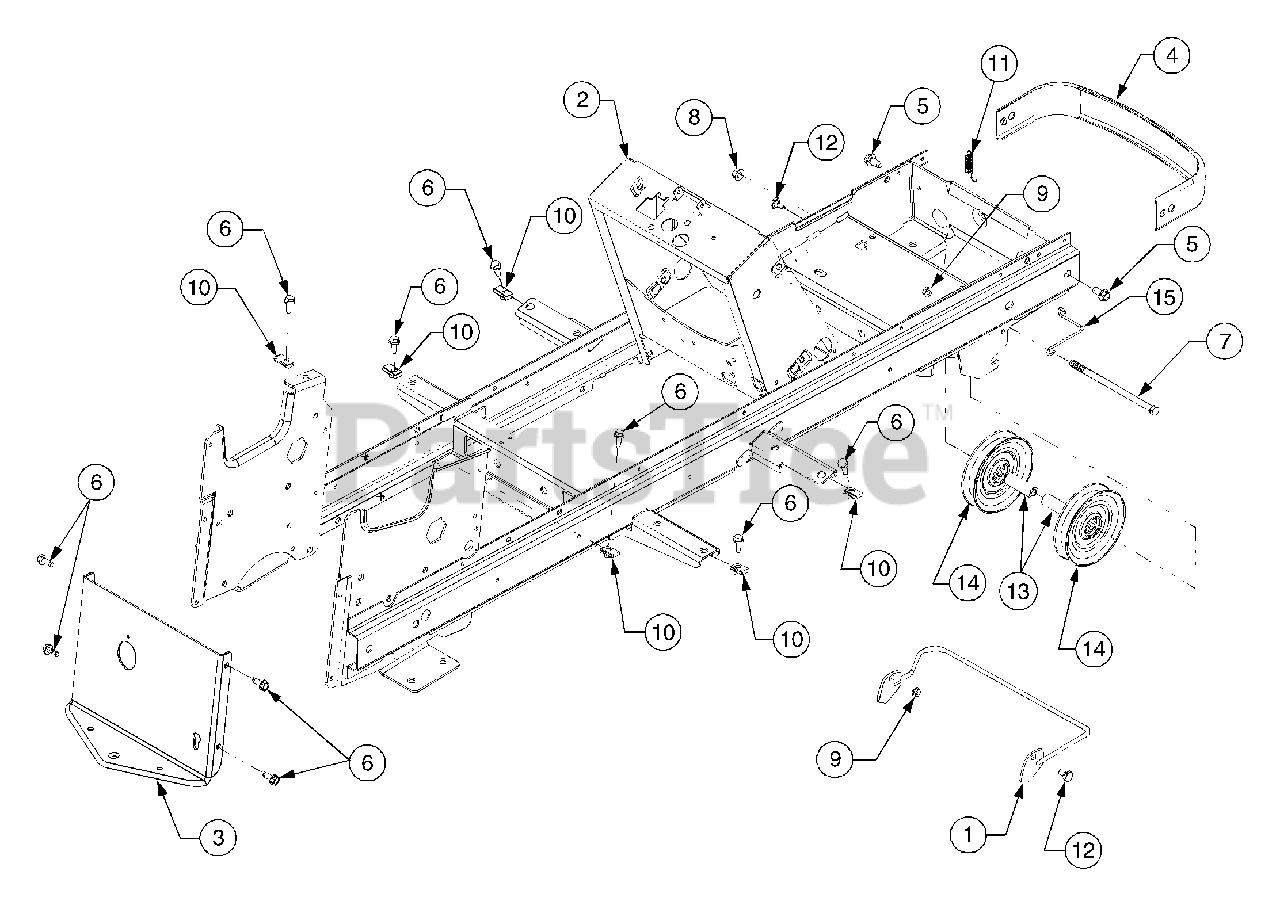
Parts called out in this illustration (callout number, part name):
6	Screw, Hex Wsh Hd Tap 5/16-18 x .75
7	Screw, Hex Cap, 3/8-16 x 7.0
8	Nut, Hex Flange Lock, 3/8-16
9	Nut, Hex Flange Lock, 1/4-20
10	U-Nut, 5/16-18
11	Spring, Latch
12	Bolt, Shoulder
13	Spacer, Idler, .411 x .720 x 2.19
14	Pulley, Idler
15	Belt Guide
